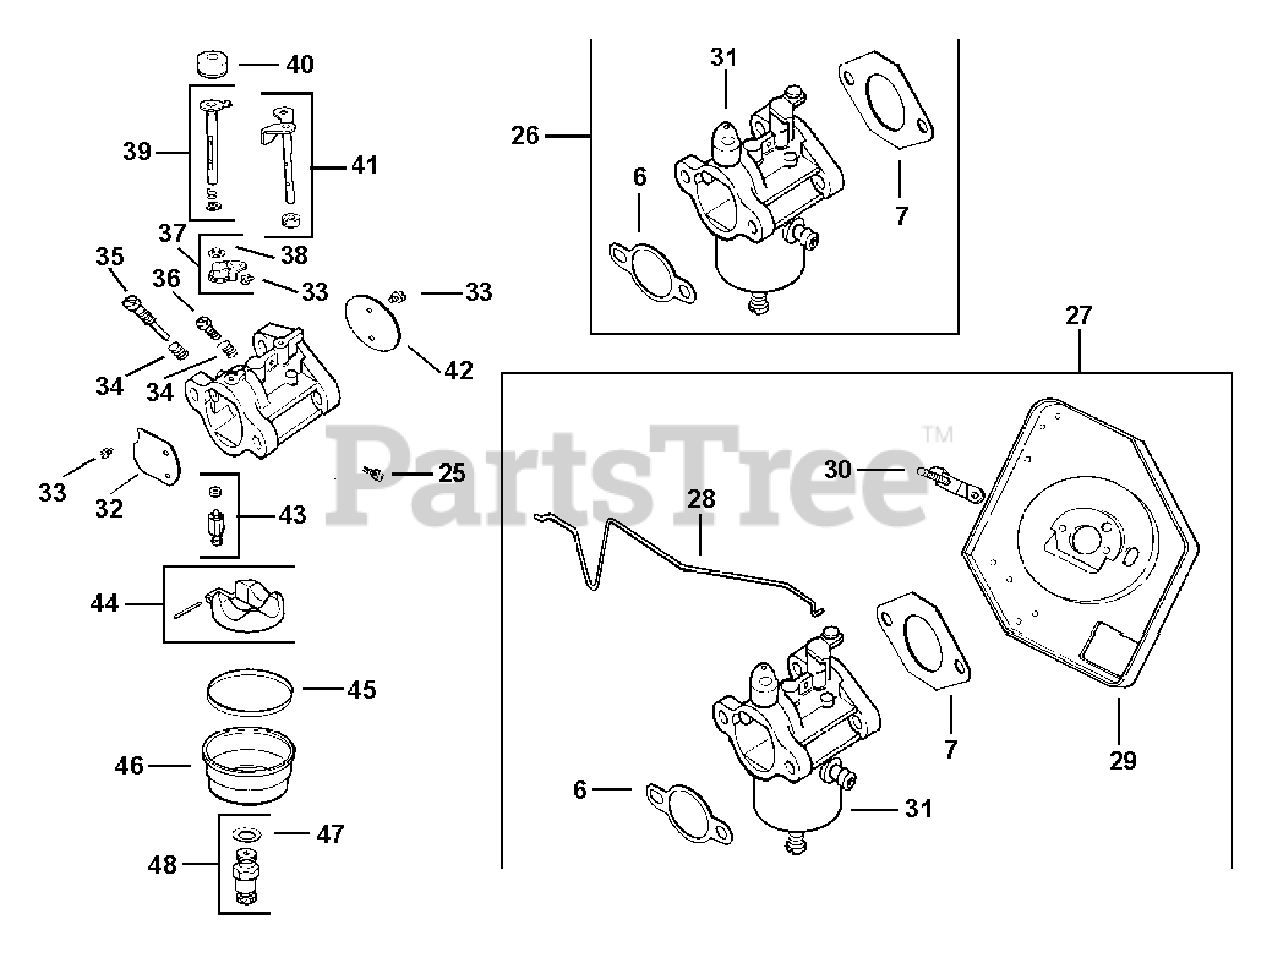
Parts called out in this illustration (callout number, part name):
6	GASKET, AIR CLEANER BASE
7	GASKET, CARBURETOR
26	CARBURETOR - USE 12 853 59
31	Carburetor assembly
32	PLATE, CHOKE
33	SCREW, VALVE
35	NEEDLE, IDLE - DISCONTINUED
37	KIT, CHOKE LEVER REPAIR - USE 12 757 32-S
38	BUSHING, CHOKE
39	SHAFT, CHOKE
40	CAP, CHOKE LEVER
41	SHAFT, THROTTLE
43	Needle and Seat
44	KIT, REPAIR FLOAT
45	GASKET, FUEL BOWL
48	KIT, HI SPEED NDLE W/GSKT-DISC.
